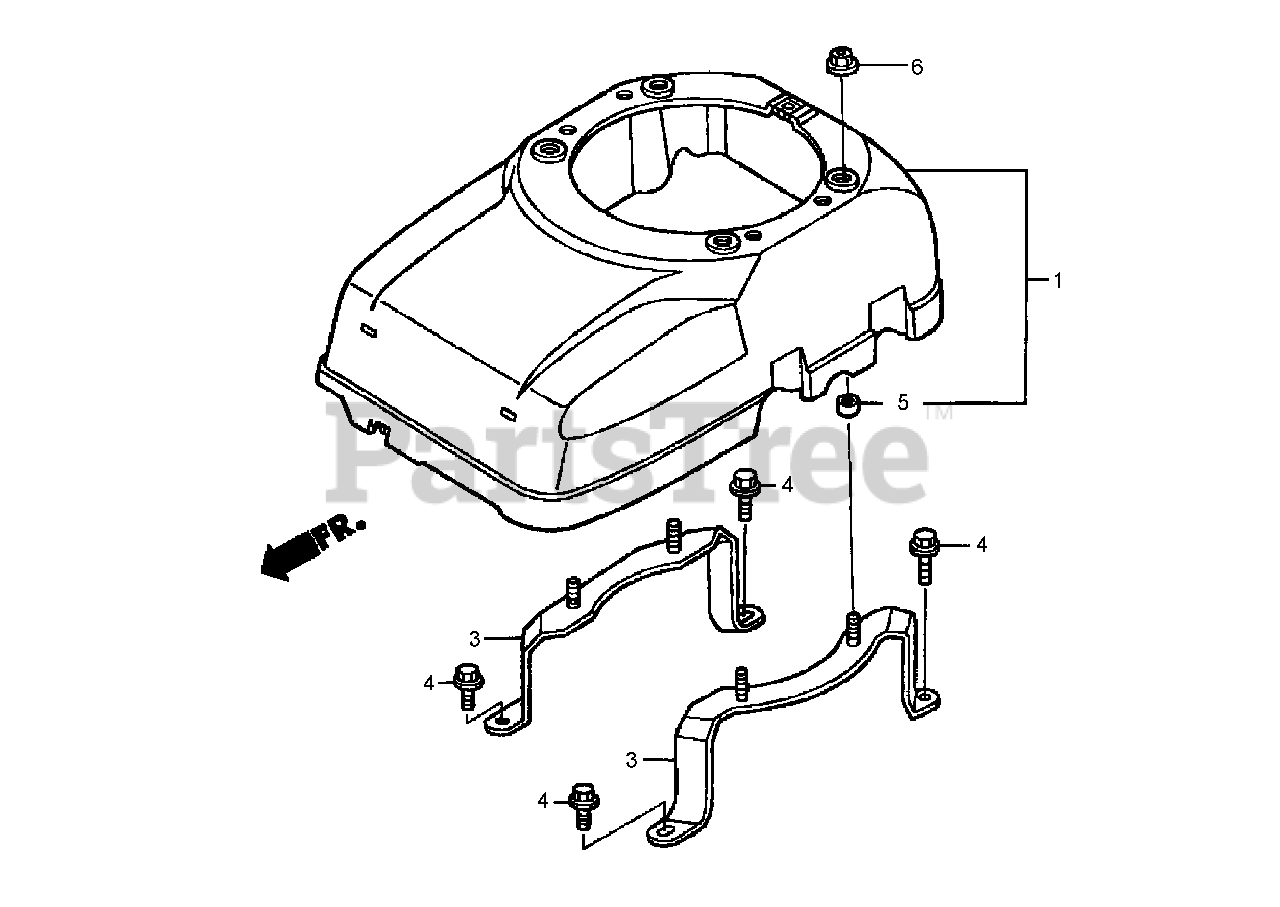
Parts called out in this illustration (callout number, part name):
1	COVER-FAN
3	BRACKET-COVER, FAN
4	BOLT-FLANGE (6X16) (C T200)
5	COLLAR-COVER, FAN
6	NUT-FLANGE (6 mm)
